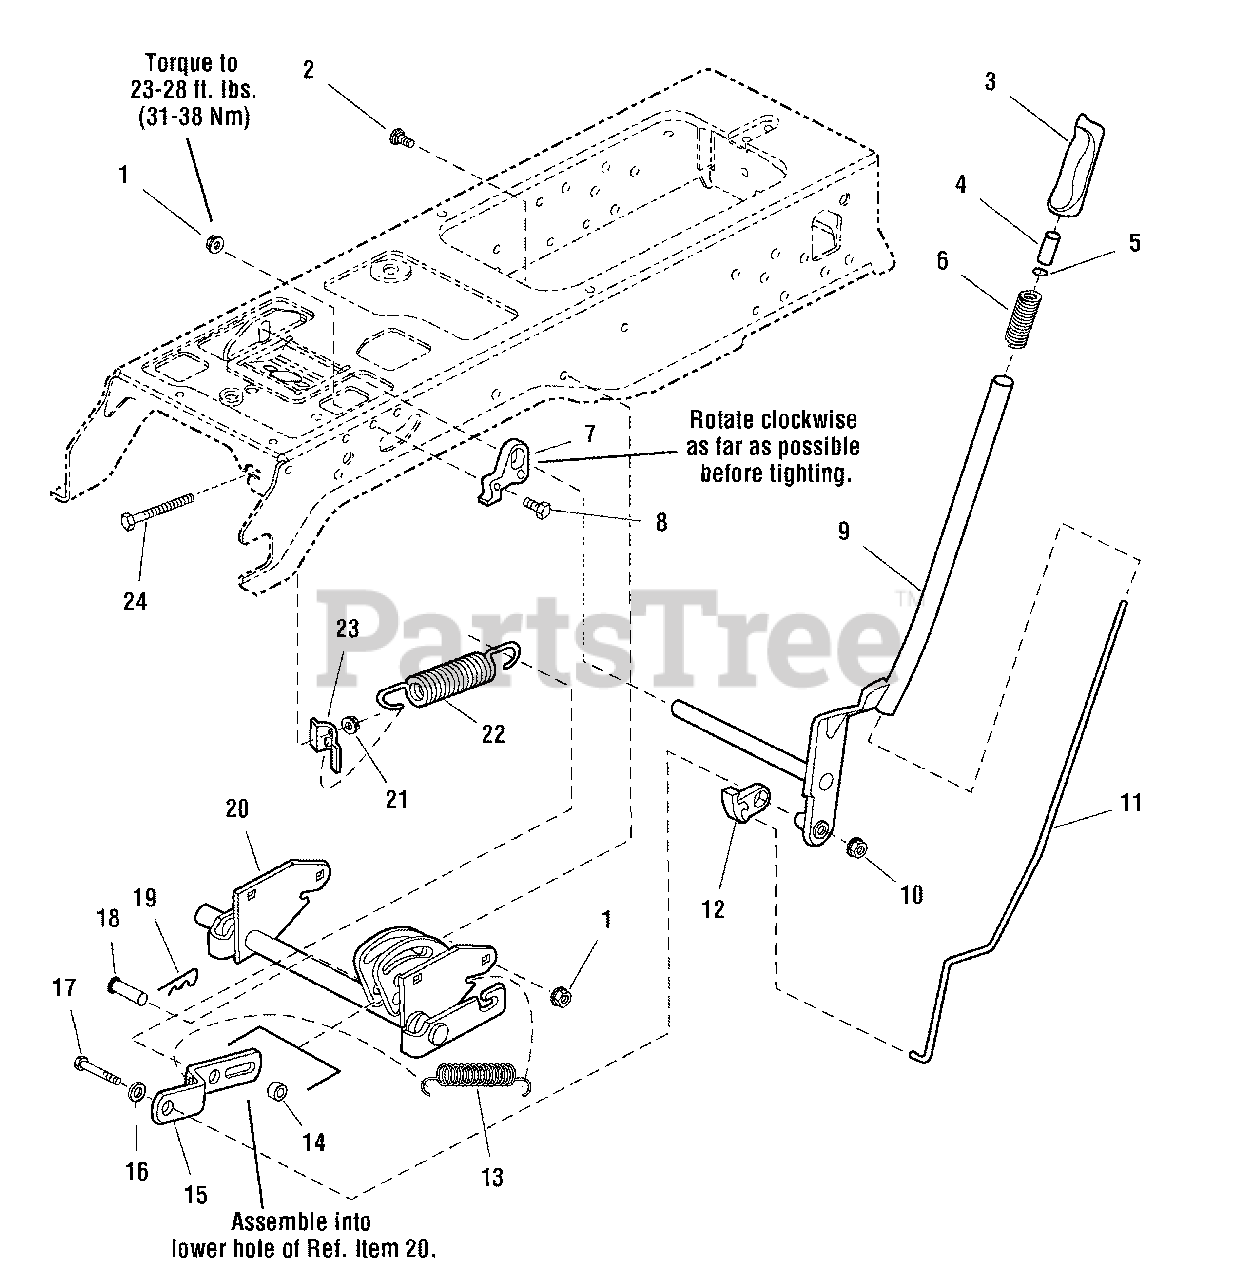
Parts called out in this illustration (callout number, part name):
1	NUT, Hex Flange Whiz-Lock, 5/16-18
2	CARRIAGE BOLT, 5/16-18 x 3/4
3	GRIP, Lift Lever
4	BUTTON, Red Nylon, for 1/4 Rod
5	NUT, Push
6	SPRING, Compression, Lift Lever
7	QUADRANT, Lift, Powdered Metal
8	CAPSCREW, Hex Head, 5/16-18 x 1, G8, Black
9	LEVER ASSEMBLY, Lift
10	NUT, Hex KEPS, 5/16-18
11	ROD, Latch
12	LOCK, Lift, Powdered Metal
13	SPRING, Extension
14	SPACER, 1/2 x 3/4 x 23/32
15	BAR, Lift, 9-7/8 Long
16	WASHER, 5/16
17	CAPSCREW, Hex Head, 5/16-18 x 2-1/4
18	PIN, Flat Head Drilled, 1/2 x 2-1/8 Long
19	CLIP, Hair Pin
20	SHAFT ASSEMBLY, Lift
21	NUT, Speed, Lug Type, 5/16-18
22	SPRING, Compression
23	RETAINER, Spring Flat
24	CAPSCREW, Hex Washer Head, 5/16-18 x 4-1/2
